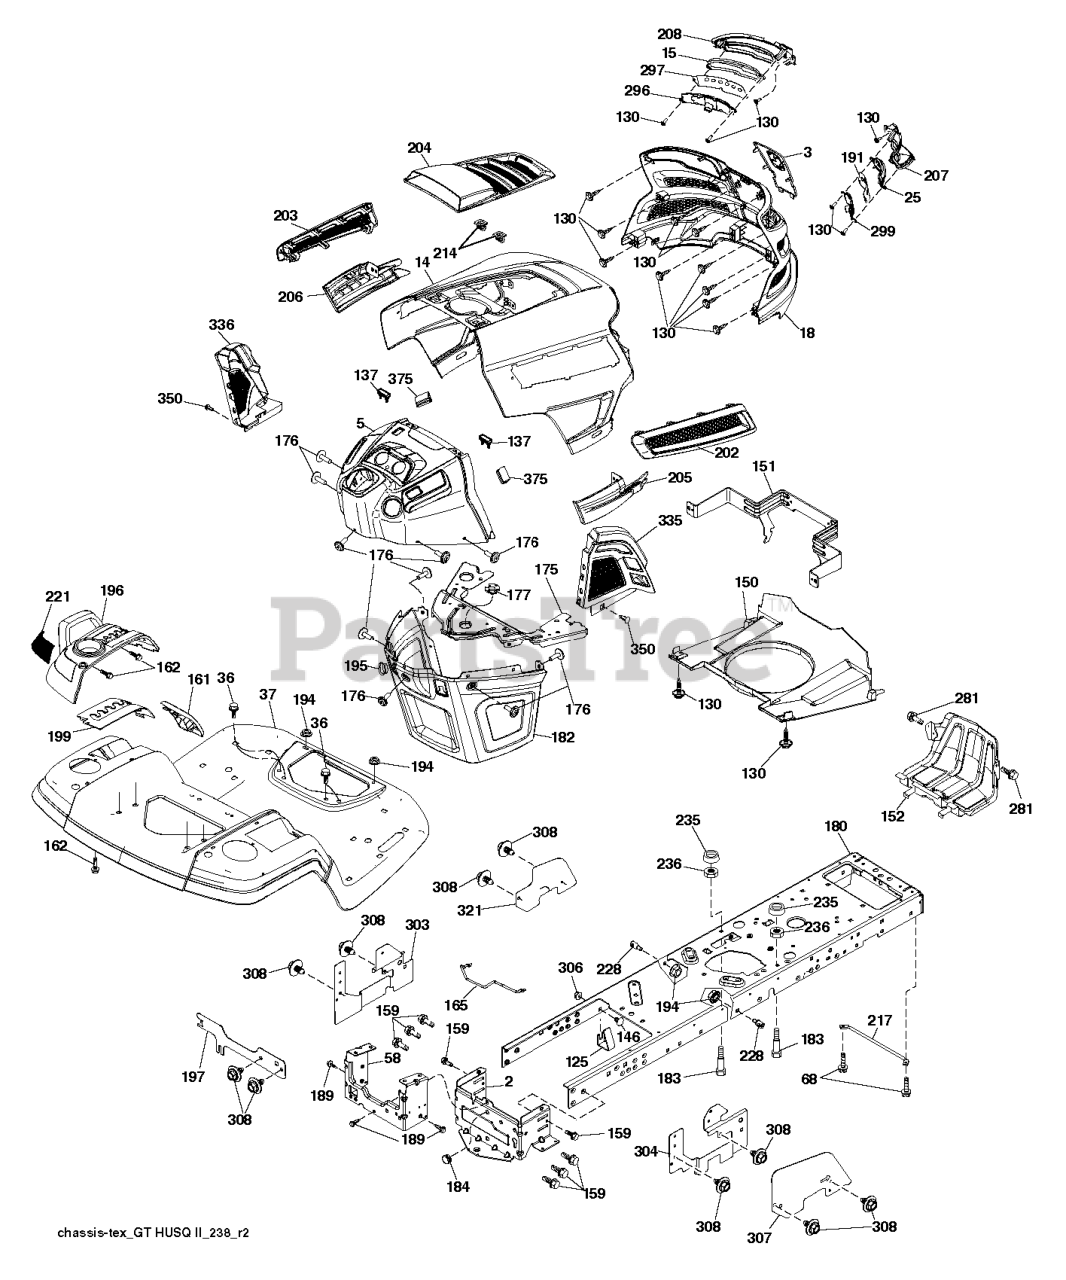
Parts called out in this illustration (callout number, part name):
2	DRAWBAR.LOWER.2PC.18/22
3	APPLIQUE.SUBASM.GT.HUSQ.II
5	DASH.UPPER.ASM.GT2.DR.EL.EFM
14	HOOD.ASM.HUSQVARNA.GT.TEX.ORAN
15	LED LIGHT.LH
18	GRILLE SUBASM.GT.II.LOW.HDLGHT
25	LENS.RH
36	SCREW 5/16"
37	FENDER.PNT.TX.GT.CH/FW/DL.HUSQ
58	DRAWBAR.UPPER.2PC,LRG.FENDER
68	SCR 5/16-18 X 1/2 SELFTAP ZN
125	CLIP.FUEL.LINE
130	SCREW.#10 X 0.750.BOS
137	BUMPER DASH
146	BOLT.RDHD.SHT.SQNK.3/8-16X5/8
150	AIR.DUCT.GTV.BLACK
151	BRACKET.PIVOT.HOOD.GT.HUSQ.II
152	SHIELD.BROWNING.PNT.GT.V2
159	SCREW, 3/8-16X3/4
161	CONSOLE.WINDOW.FUEL.HUSQ.GT
162	SCREW.HI-LO.CONSOLE
165	SUPPORT.TANK.REAR.B/TE
175	PLATE.PNT.CROSSMEMBER.HUSQ/PRE
176	SCREW.#10-24X5/8.RN.QU
177	BUSHING STEERING
180	CHASSIS.LT/GT.BOLTED
182	DASH.LOWER.COMMON.12V.ADAPTOR
183	BOLT.5/16-18X1-1/4 FULL THD
184	PLUG.DEMO.625
189	SCREW
191	INSERT INFLECT.RH
194	NUT LOCK HEX FLANGE 5/16-18
195	PLUG.HOLE.DASH.LOWER.12V.BLK
196	SUBASM.CONSOLE.HUSQ.GT.DECKLFT
197	SHIELD.DRAWBAR.LT.REAR.TANK
199	PLATE.DECK.LIFT.HUSQVARNA.GT
202	VENT.SIDE.RH.GT.HUSQ.II.
203	VENT.SIDE.LH.GT.HUSQ.II.498
204	VENT.TOP.HUSQ.GT2
205	SIDE.TRIM.RH.GT.HUSQ.II
206	SIDE.TRIM.LH.GT.HUSQ.II.GRAY
207	LIGHT.BEZEL. RH
208	LIGHT.BEZEL.LH
214	CLIP.RETAINER.TINNER.
217	ROD.PIVOT.HOOD
221	REFLECTOR.LH.TEX GT HU
228	STUD.FASTNER.W/ANTI-ROTATE
235	SPACER FENDER
236	NUT.CENTERLOCK.5/16-
281	SCREW 3/8-16X1
296	LED LIGHT.LH
297	INSERT REFECT LH
299	LED LIGHT.RH
303	SHIELD.LWR.LH.LTGT.NON30
304	SHIELD.LWR.RH.LTGT.NON30.NOTCH
306	NUT LOCK FLG 3/8-16 UNC
307	SHIELD.UPPER.RH.GT
308	BOLT.5/16-18UNCX3/4 W/SEMS.BLK
321	SHIELD.UPPER.LH.GT
335	COVER.LOWER.DASH.RH.BLACK
336	COVER-LH.LOWER.DASH.GT2.BLACK
350	CLIP.X-MAS.TREE
375	BUMPER CLIP-ON. DASH 1"
